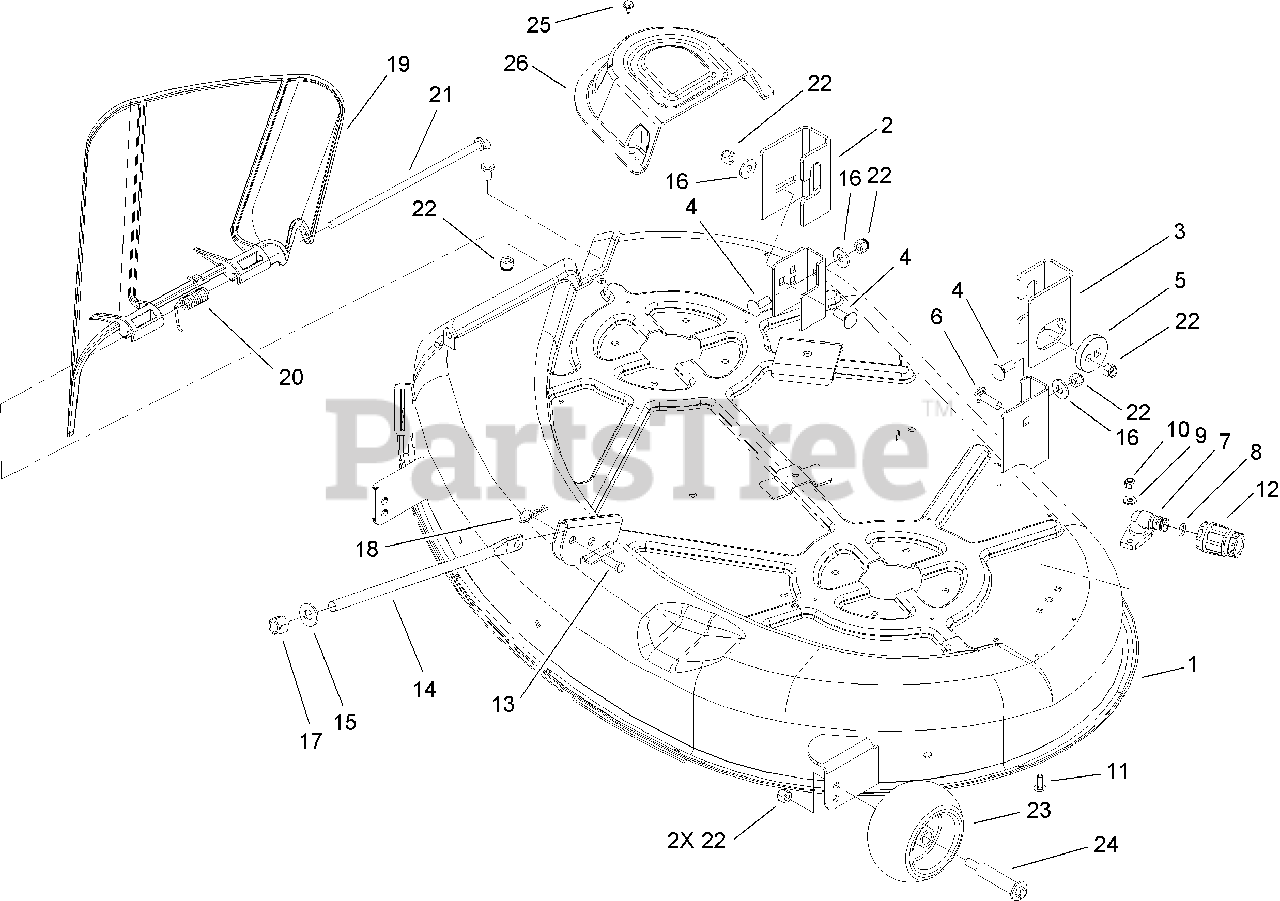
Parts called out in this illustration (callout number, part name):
1	42 INCH DECK ASM
2	BRACKET-HANGER, RIGHT REAR
3	BRACKET-HANGER, LEFT REAR
4	SCREW-CARR
5	ECCENTRIC
6	SCREW-CARR
7	FITTING-WASHOUT
9	WASHER-FLAT
10	NUT-LOCK, NI
11	SCREW-CARR
12	CONNECTOR-HOSE
13	PIN-CLEVIS
15	WASHER-THRUST
16	WASHER-HARDENED
17	NUT-LOCK, NI
18	PIN-HAIR
19	DEFLECTOR-42 INCH
20	SPRING-TORSION
21	ROD-PIVOT
22	NUT-LOCK, NI
23	ROLLER-SCALP, ANTI
24	BOLT-SHOULDER
26	COVER-BELT
